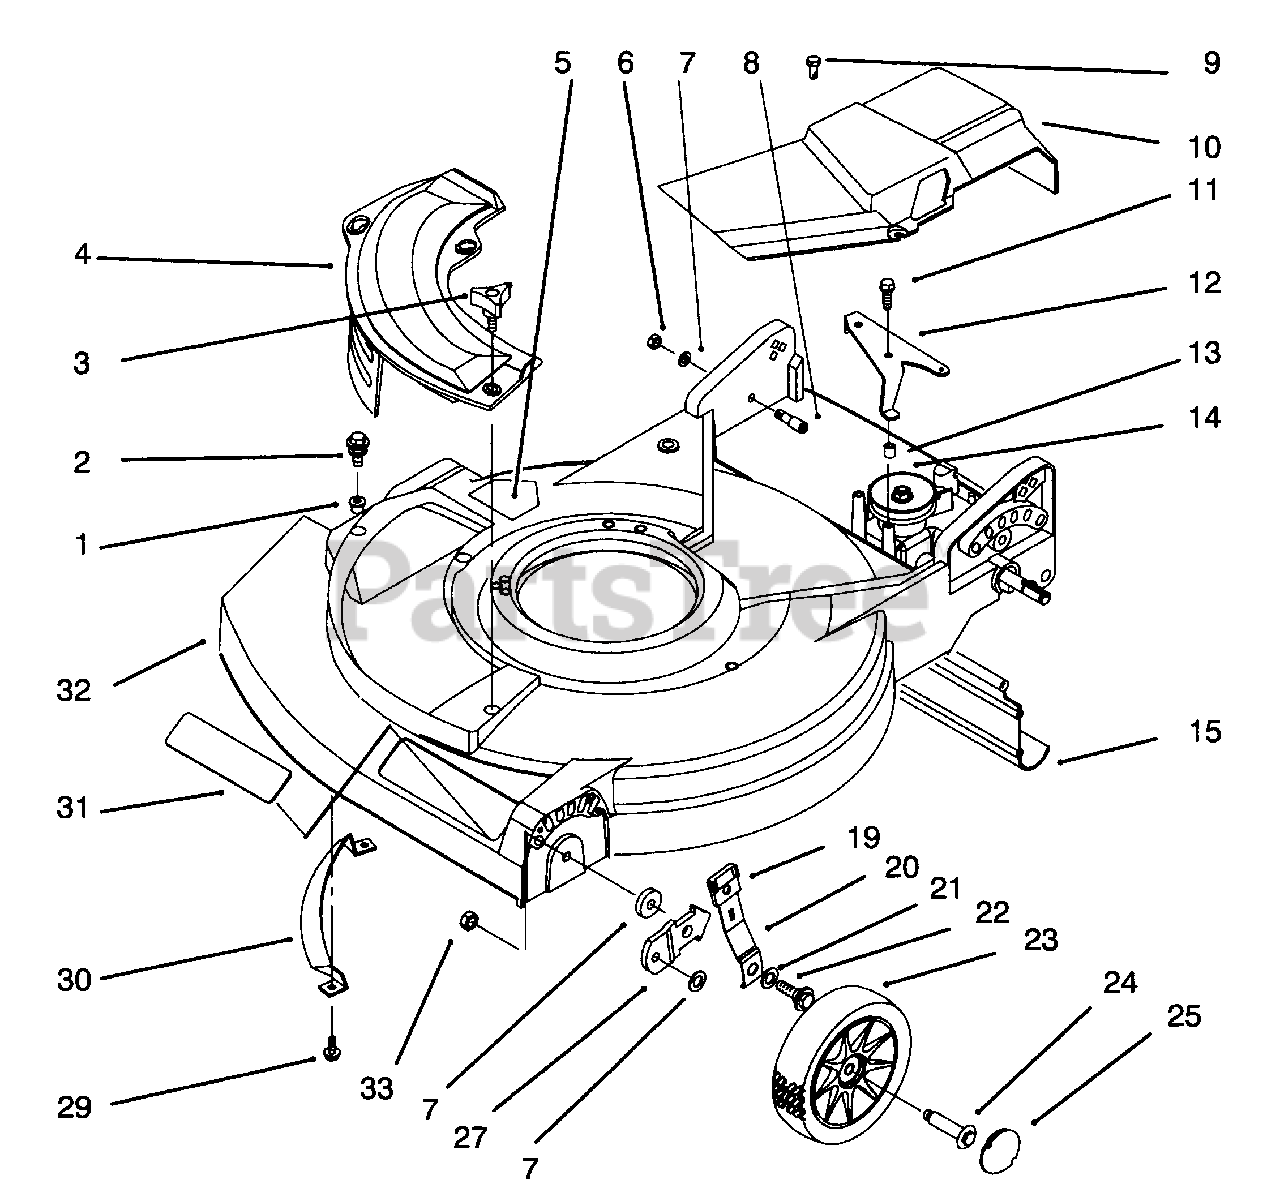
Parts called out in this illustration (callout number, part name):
1	Grommet
2	Screw-Thread Forming
3	Knob
4	Cover-Plate, Mulch
5	Decal-Danger (English)
7	Washer-Wheel Bolt
8	Bolt-Shoulder
10	Cover-Drive
11	Screw
12	Bracket-Actuator
14	Gear Case Assembly
15	Shield-Trailing
19	Knob-Spring Arm
20	Spring Arm Assembly
21	Washer-Belleville
22	Bolt-Shoulder
23	Wheel-6"
24	Bolt-Wheel
27	Bracket-H.O.C.
30	Bar-Toe
31	Applique
32	Housing-21 (Incl. Ref. #5 & 31)
33	Nut-Lock
